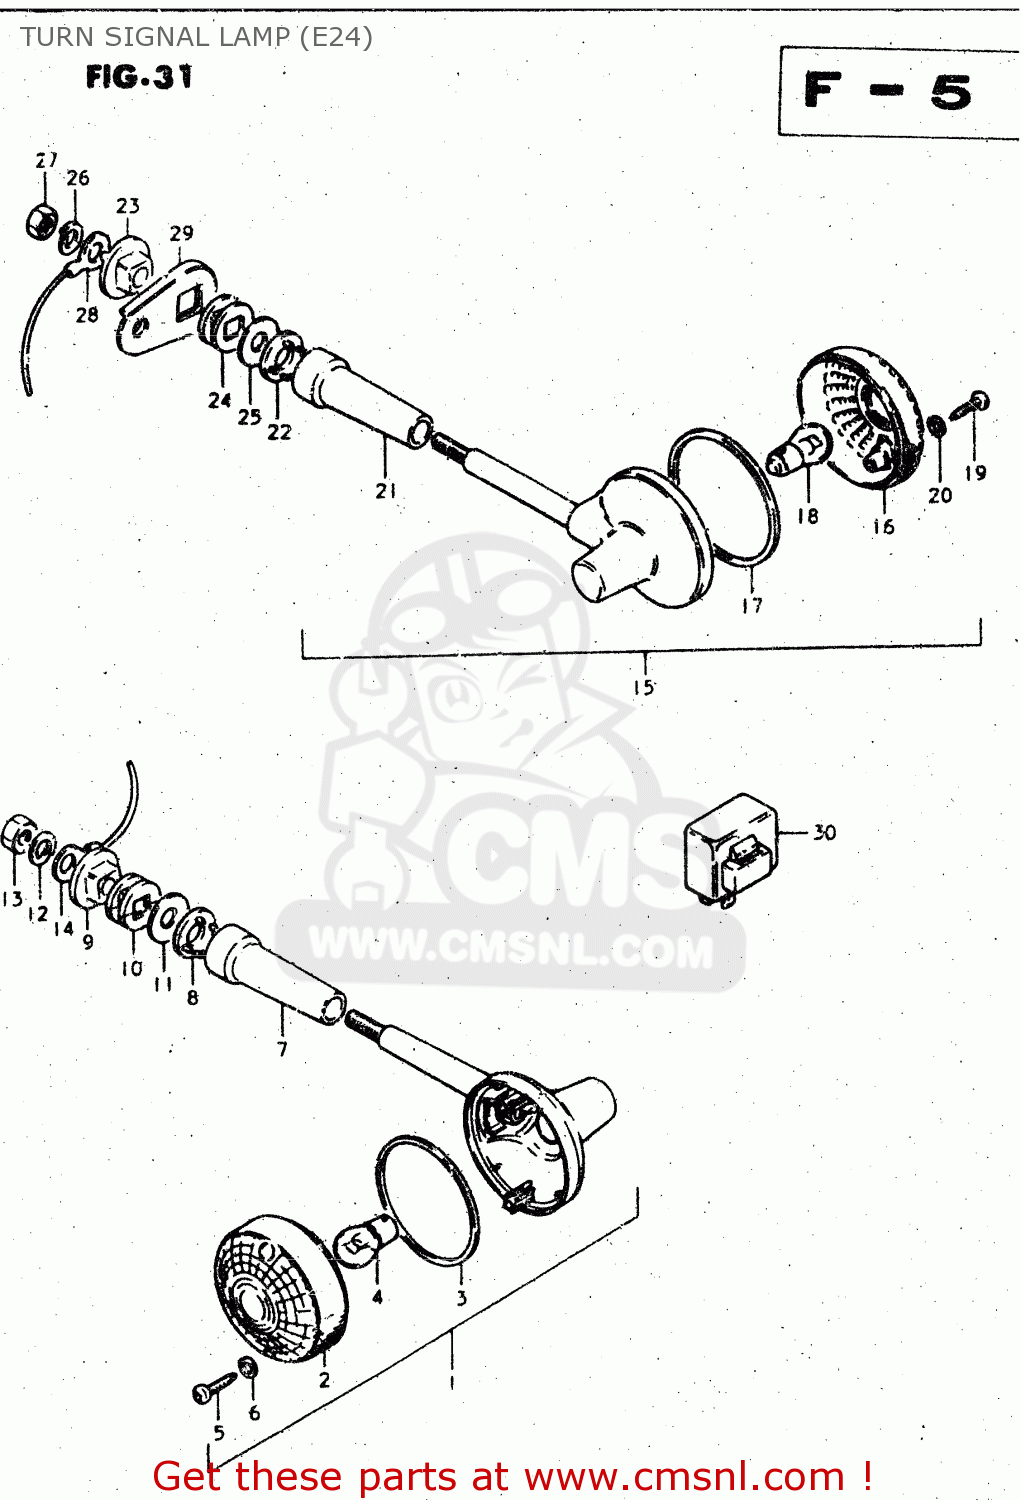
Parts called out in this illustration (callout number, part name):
1	LAMP, REAR TURN SIGNAL
2	LENS
3	GASKET (NAS)
4	BULB(12V23W,STANLEY,A4577A)
5	SCREW
6	GASKET (NAS)
7	COVER,STAY
8	SPACER
9	SPACER
10	CUSHION
11	WASHER (10.5X30X2.3)
12	LOCK WASHER
13	NUT
14	LEAD WIRE,EARTH
15	LAMP, REAR TURN SIGNAL
16	LENS
17	GASKET (NAS)
18	BULB(12V23W,STANLEY,A4577A)
19	SCREW
20	GASKET (NAS)
21	COVER,STAY
22	SPACER
23	SPACER
24	CUSHION
25	WASHER (10.5X30X2.3)
26	LOCK WASHER
27	NUT
28	LEAD WIRE,EARTH
29	BRACKET,RR TURN SIGNAL LAMP
30	RELAY,TURN SIGNAL
